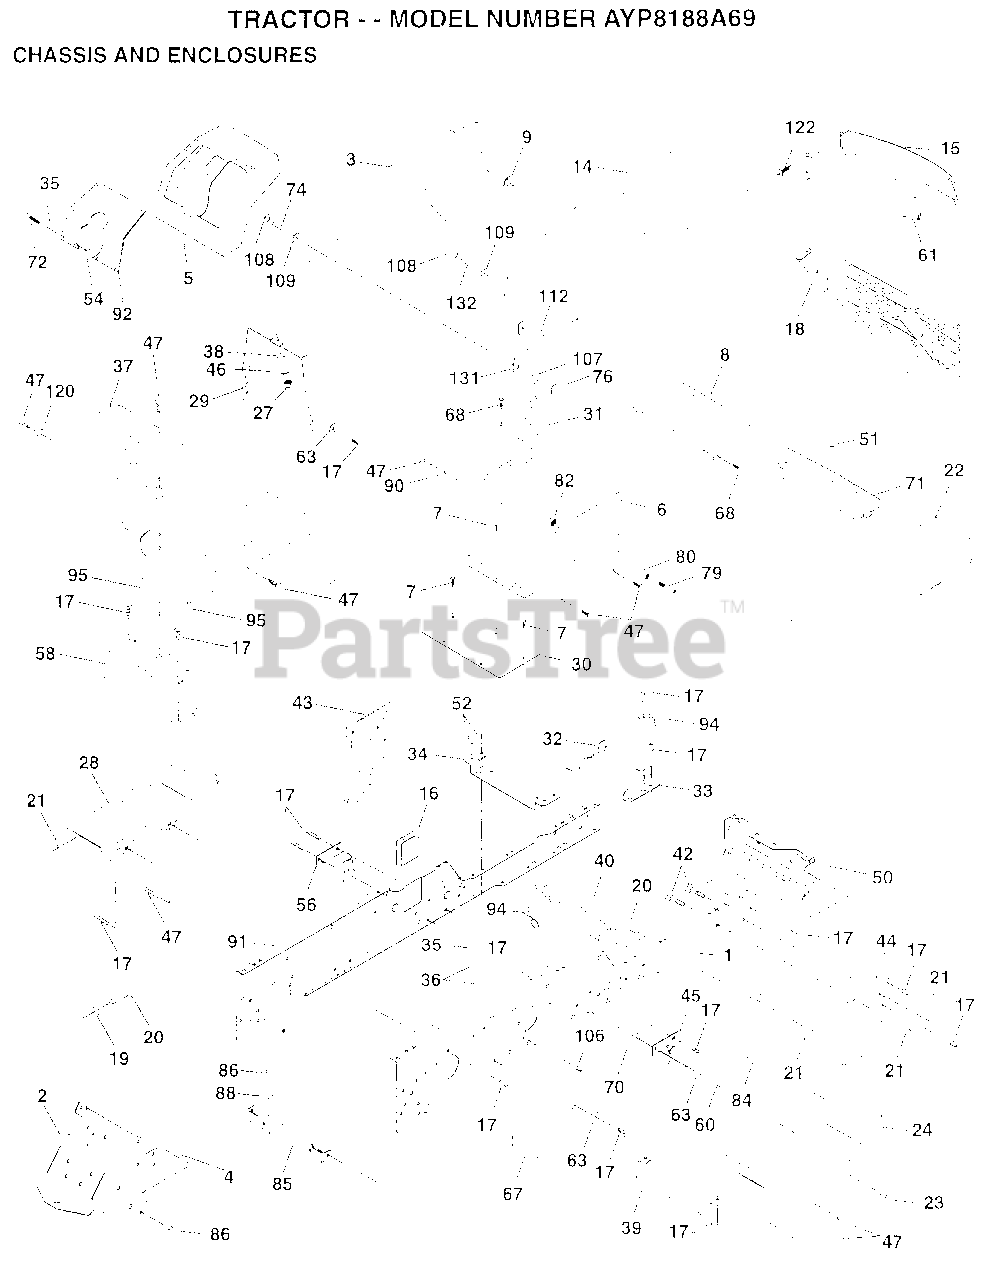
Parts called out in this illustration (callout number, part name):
1	"RAIL,FRAME RH"
2	DRAWBAR GT
3	"PANEL,ASM SIDE LH"
4	NUT.7/16
5	DASHBOARD BLACK
6	"DASH AS.,LOWER"
7	SCREW
8	SUPPORT.DASH.BTRY
9	PAL NUT LT
14	"HOOD ASM.,PNT"
15	LENS.BAR.CLEAR
16	COVER ACCESS
17	SCREW
19	WASHER
20	BOLT
22	PANEL ASM.SIDE RH
23	SCREW GTV
24	FOOTREST.RH.LT/GT
28	FOOTREST.LT.LT/GT
29	DASH.SUPT.YP/HUSQ
30	SADDLE.SCR.6SP
31	BRAKET.SUPT.STEER
32	BRACKET ASM FRAME
33	BRACKET ASM FRAME
34	BRACKET.ENG.SUPT.
35	WASHER
36	BOLT
37	"FENDER,RH"
38	LOCKWASHER
39	BRACKET.AXLE.FRT.
43	BRACKET.SUS.FT.LH
44	BRACKET.SUS.FT.RH
46	WASHER PM
47	SCREW LT
50	BRACKET.CHASSIS.
51	SCREW CRT
58	BRKT.ASM.FENDER
60	SCREW
61	BEZEL.ASM.
63	WASHER
67	GUIDE BELT TRANS
68	SCREW LT
70	GUIDE.BELT.MID.SP
72	SCREW
74	SCREW
76	WELDNUT
79	SCREW
80	SPACER LT
84	STOP.OVER.CENTER
85	BRACKET.SUPT.TRAN
86	BOLT
88	LOCKWASHER
90	LOCKWASHER
91	"RAIL,FRAME LH"
92	PLATE SLKSCR YP
94	CLIP GTV
95	NUT-PUSH YT
107	HOOD LATCH T
108	SNAP CAP LT
109	WASHER LT
112	ACORN NUT RB
120	WASHER HYT
124	NUT
131	BKT.SPT.HOOD/PANL
132	SCREW.10-24X3/8.
